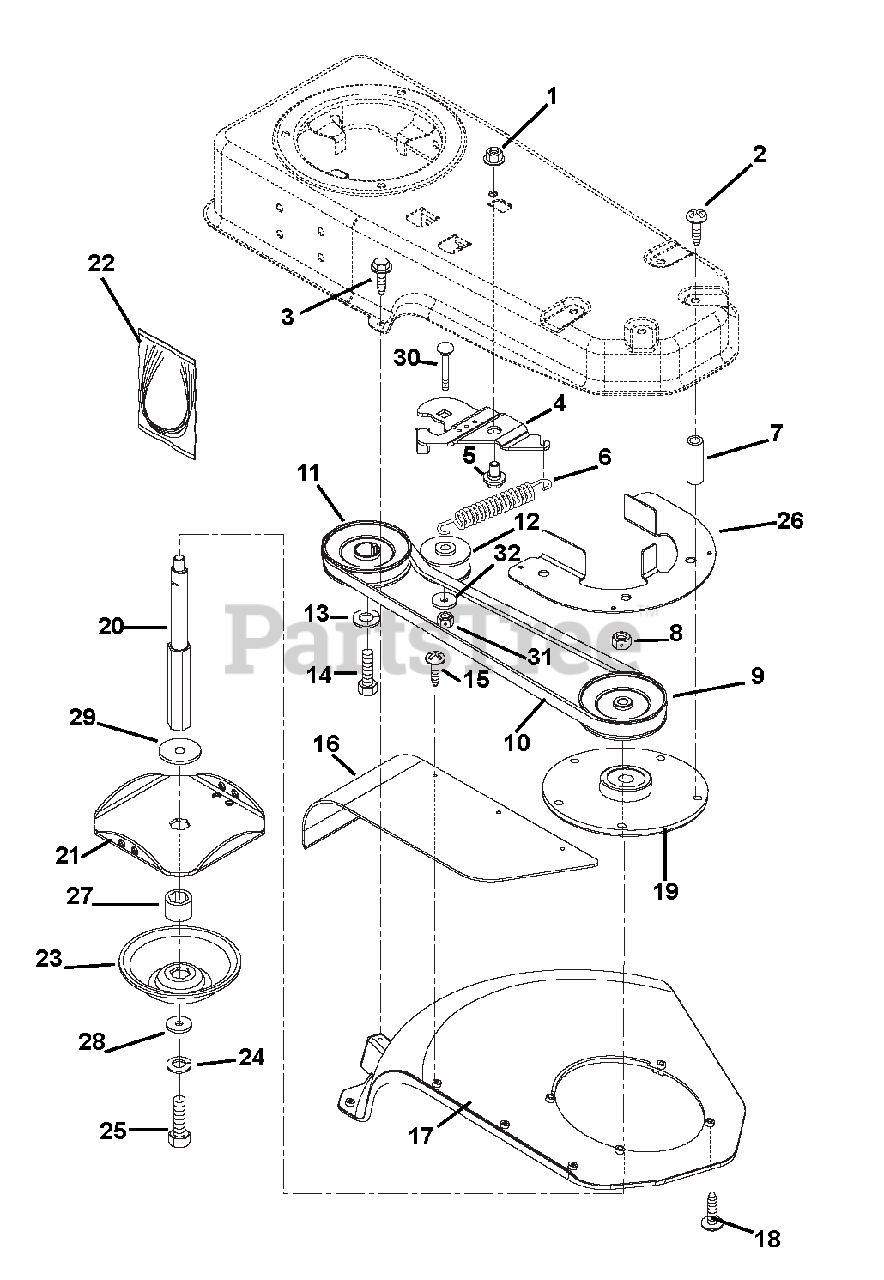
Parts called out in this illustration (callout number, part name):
1	NUT-LK-CTR-FLG .38-16 YWZC
2	@SCR-TAP.375-16X2.75 HWH TR YZ
3	SCR-TAP 10-24X.75 HWH TR YWZC
4	BRACKET - IDLER
5	BOLT-SHLDR .375-16X.150
6	SG-TENS .035X.45X2.75 WLD 3.5
7	BSHG-SPCR .406X.625X1.90
8	NUT-LK-FLG .375-24 GR5 YWZC
9	PLY-V 3.50 OD X .87 WIDE (CUT)
10	V-BELT, HA-RAW EDGE
11	SHEAVE-ENGINE 3.50 ODX.87 WIDE
12	IDLER - FLAT 1.875OD X .75WIDE
13	@WSHR-LK .38X.094 REG YWZC
14	BLT-HEX .38-24X1.0 YWZC GR5
15	SCR-TAP #10-16 X .625 HWH
16	GUARD - DEBRIS
17	SHIELD - TRIMMER
18	SCR-TAP 10-24X.75 HWH TR YWZC
19	HOUSING - JACKSHAFT
20	SHAFT - CUTTER - HEX
21	DISC - CUTTER - HEX
22	LINE - CUTTER 18" LG PKG OF 6
23	GUIDE - HEIGHT - HEX
24	@WSHR-LK .31X.078 REG YWZC
25	@BLT-HEX .31-18X.75 GR5 YWZC
26	FINGER,BELT,ARIENS ORANGE
27	SPACER - HEX
28	WSHR-FL-STL .344X1.125X.135
29	SHIELD - DUST
30	@BLT-RHDSSQNK .38-16X1.50 G5YZ
31	@NUT-LK-CTR .38-16 YWZC
32	@WSHR-FL-STL.406X.812X.065 YWZ
